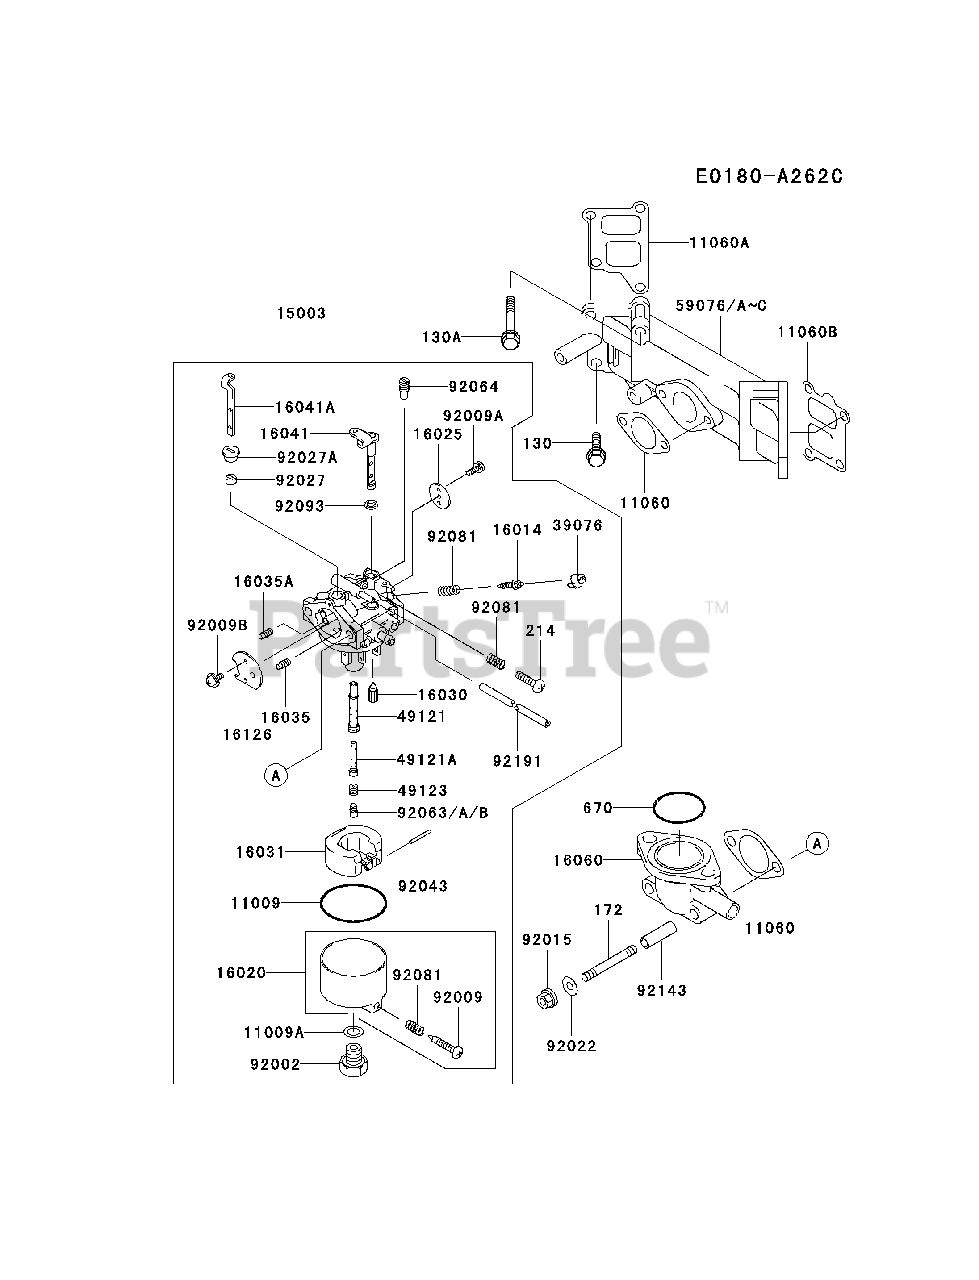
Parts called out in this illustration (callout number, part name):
130	BOLT-FLANGED
130A	BOLT-FLANGED
172	BOLT-STUD
214	SCREW-PAN+-
670	O RING
